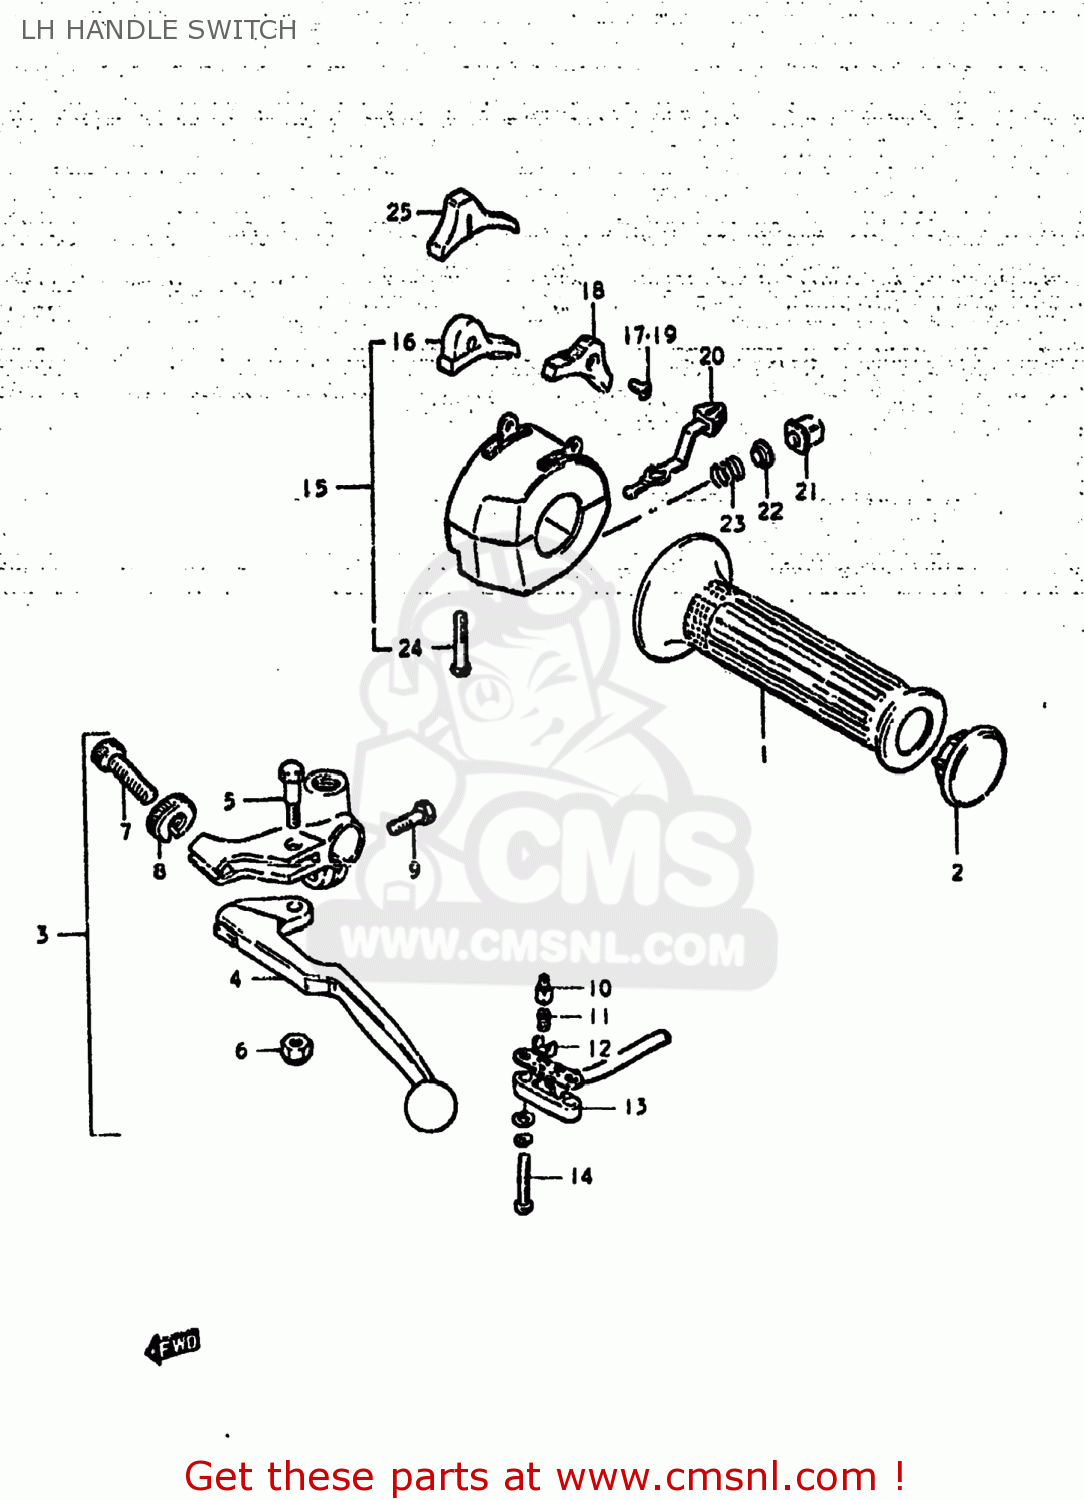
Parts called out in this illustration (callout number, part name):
1	GRIP,LEFT
2	CAP,GRIP END
3	LEVER ASSEMBLY
4	LEVER,CLUTCH
5	BOLT,LEVER
6	NUT 6MM
7	ADJUSTER,CABLE
8	NUT,CABLE ADJUSTER
9	BOLT,CLUTCH LEVER HOLDER
10	HOLDER
11	SPRING
12	PLATE
13	COVER,FR BK TERMINAL BASE
14	SCREW
15	SWITCH ASSY,HANDLE,L
16	KNOB,STOP
17	SCREW
18	KNOB,DIMMER SWITCH
19	SCREW
20	KNOB,TURNSIGNAL
21	BUTTON,HORN
22	CONTACT
23	SPRING
24	SCREW
25	KNOB,LIGHTING SWITCH
